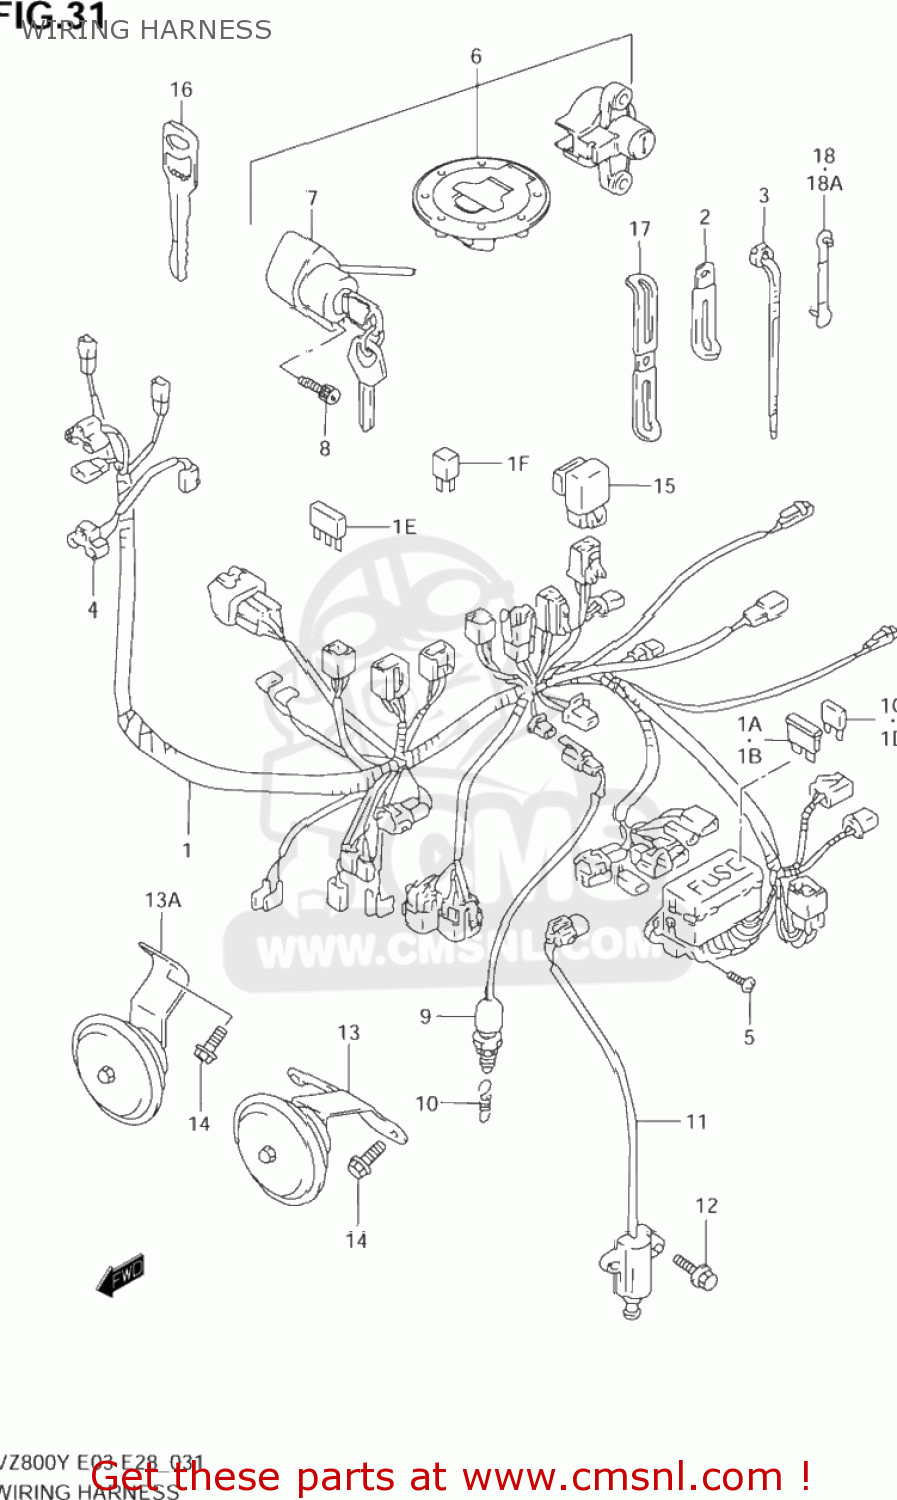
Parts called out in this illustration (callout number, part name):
1	HARNESS,WIRING
1A	FUSE(10A)
1B	FUSE(15A)
1C	FUSE(10A)
1D	FUSE(15A)
1E	DIODE(STANLEY DE8804)
1F	RECTIFIER ASSY
2	CLAMP(L:65)
3	CLAMP(L:95)
4	LEAD WIRE,HEADLAMP
5	SCREW 6X12
6	LOCK SET
7	SWITCH ASSEMBLY,IGNITION
8	BOLT(6X15)
9	SWITCH ASSY,STOP LAMP
10	SPRING
11	SWITCH ASSY,SIDE STAND WARNING
12	BOLT
13	HORN ASSY
13A	HORN ASSY
14	BOLT
15	RELAY ASSY
16	KEY,BLANK
17	CLAMP,STARTER MOTOR LEAD
18	CLAMP(L:63)
18A	CLAMP(L:33)
